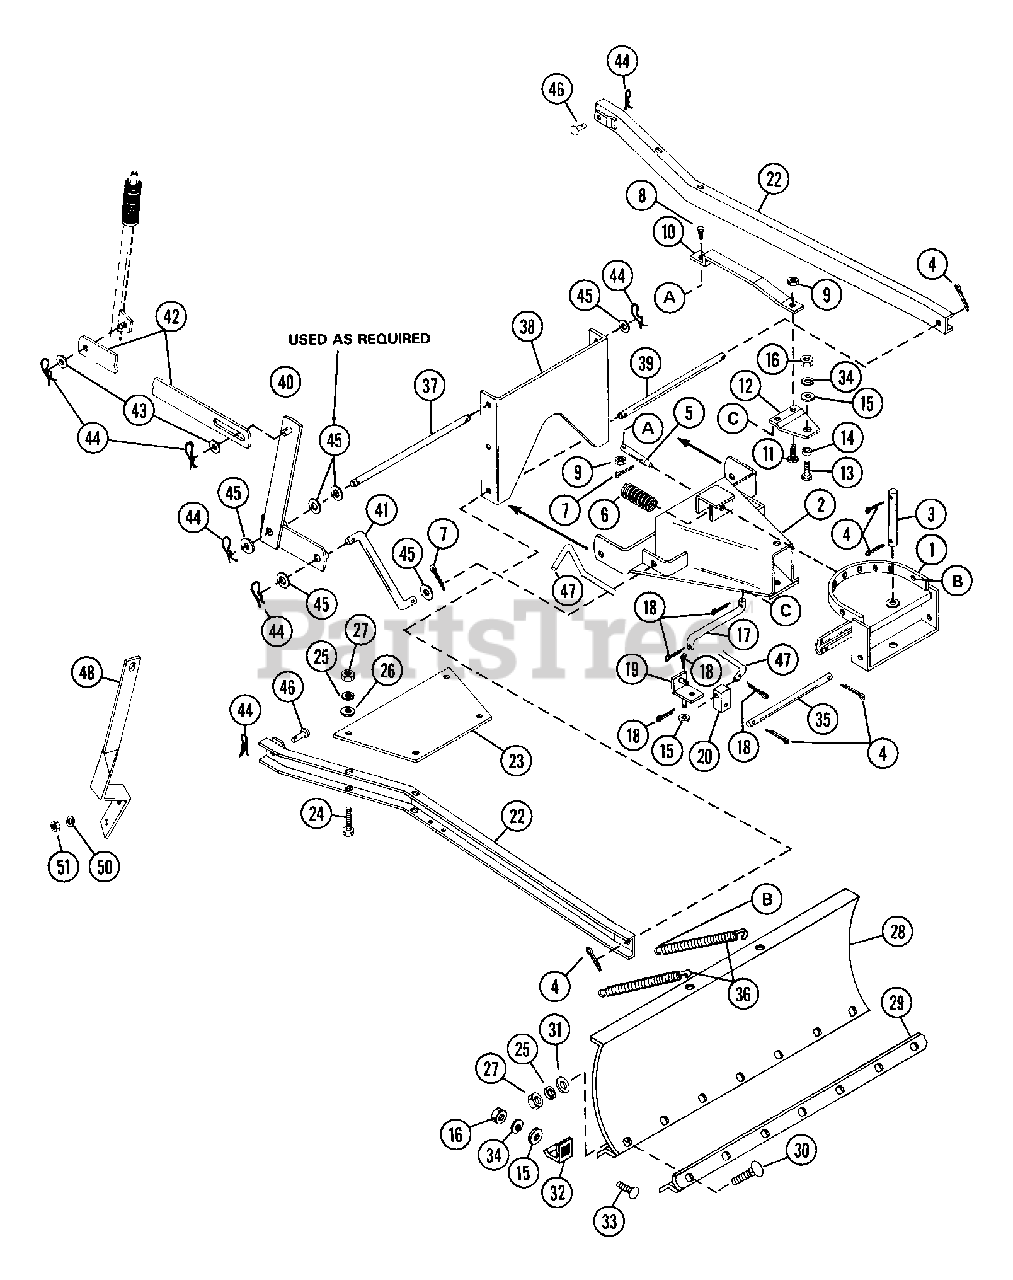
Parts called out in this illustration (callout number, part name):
1	SUPPORT
2	PUSH FRAME
4	PIN-COTR .18X1.0 PL
5	LATCH PIN
6	SG-COMP .080X.85X1.44
7	PIN-COTR .12X1.0 PL
8	BLT-HEX .31-18X1.25 PL GR2
9	NUT-LK .312-18 GR A PL
11	BLT-RDHDSQNK .312-18X.62SHTPL
12	PIVOT PLATE
13	BLT-HEX .38-16X1.00 PL
14	SPACER .406X.749X.162
15	WSHR-FL-STL .438X1.0X.083 PL
16	NUT-HEX .375-16
18	PIN-COTR .12X.75 PL
20	UNIVERSAL BLOCK JOINT
22	CHANNEL
23	STIFFENER PLATE
24	BLT-HEX .31-18X2.50 PL GR5
25	WSHR-LK .312X.097 PL HVY
26	WSHR-FL-STL .323X.625X.062 PL
27	NUT-HEX .312-18
28	WELDMENT, SNOW BLADE
29	WEAR PLATE
30	BLT-RDHDSQNK .31-18X1.00 PL
31	WSHR-FL-STL .38X.875X.083 PL
32	SKID SHOE
33	BLT-RDHDSQNK .38-16X1.0 PL
34	WSHR-LK .375X.094 MED PL
36	SG-TENS .187X1.50X9.94 WLD 40
37	MOUNT ROD
38	PIVOT SUPPORT
39	PIVOT ROD
40	LIFT BELLCRANK
41	LIFT LINK
42	LIFT STRAP
43	WSHR-FL-STL .531X1.062X.095 PL
44	PIN-HAIR INT .09X.188 PL
45	WSHR-FL-STL.656X1.312X.095 PL
46	PIN-CLEV .494X1.25 YWZC
47	CONTROL ROD
48	CONTROL SUPPORT
50	WSHR-LK .312X.097 PL HVY
51	NUT-HEX .312-18
52	BLT-RDHDSQNK .25-20X1.00 GR5
53	WSHR-LK .250X.077 HVY PL
54	NUT-WING .250-20 YWZC
